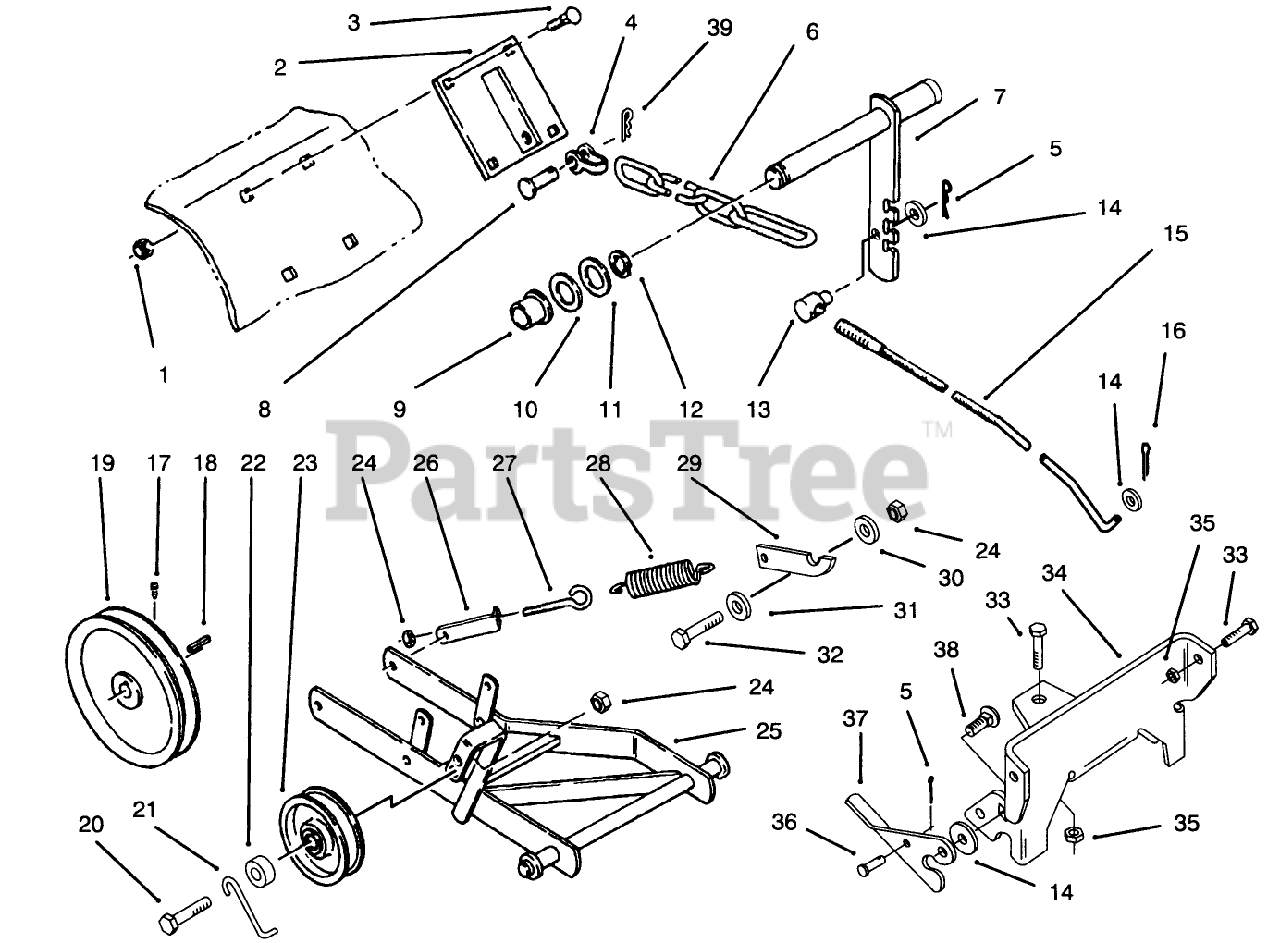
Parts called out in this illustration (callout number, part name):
1	NUT-LOCK, NI
2	HITCH ASM
3	BOLT-CARR
4	Assembly-Clevis (Incl. Ref.# 5 & 8)
5	Hairpin
6	CHAIN-LIFT
7	LEVER ASM
8	Clevis Pin
9	BUSHING-BRONZE
10	WASHER
11	WASHER-SHIM
12	E-RING
13	TRUNNION-CLUTCH ROD
14	WASHER-FLAT
15	ROD-LIFT
16	PIN-COTTER
17	SCREW-SQH
18	KEY-STRAIGHT
19	PULLEY
20	SCREW-HH
21	GUIDE-BELT
22	SPACER
23	PULLEY-IDLER
24	NUT-LOCK, NI
25	HITCH ASM RED
26	BRACKET - SPRING RED
27	EYEBOLT
28	SPRING
29	CATCH-SPRING
30	SPACER
31	WASHER
32	SCREW-HH
33	SCREW-HH
34	BRACKET-MOUNTING
35	NUT-LOCK, NI
36	Pin
37	PLATE-LATCHING
38	BOLT-CARR
39	PIN-COTTER
